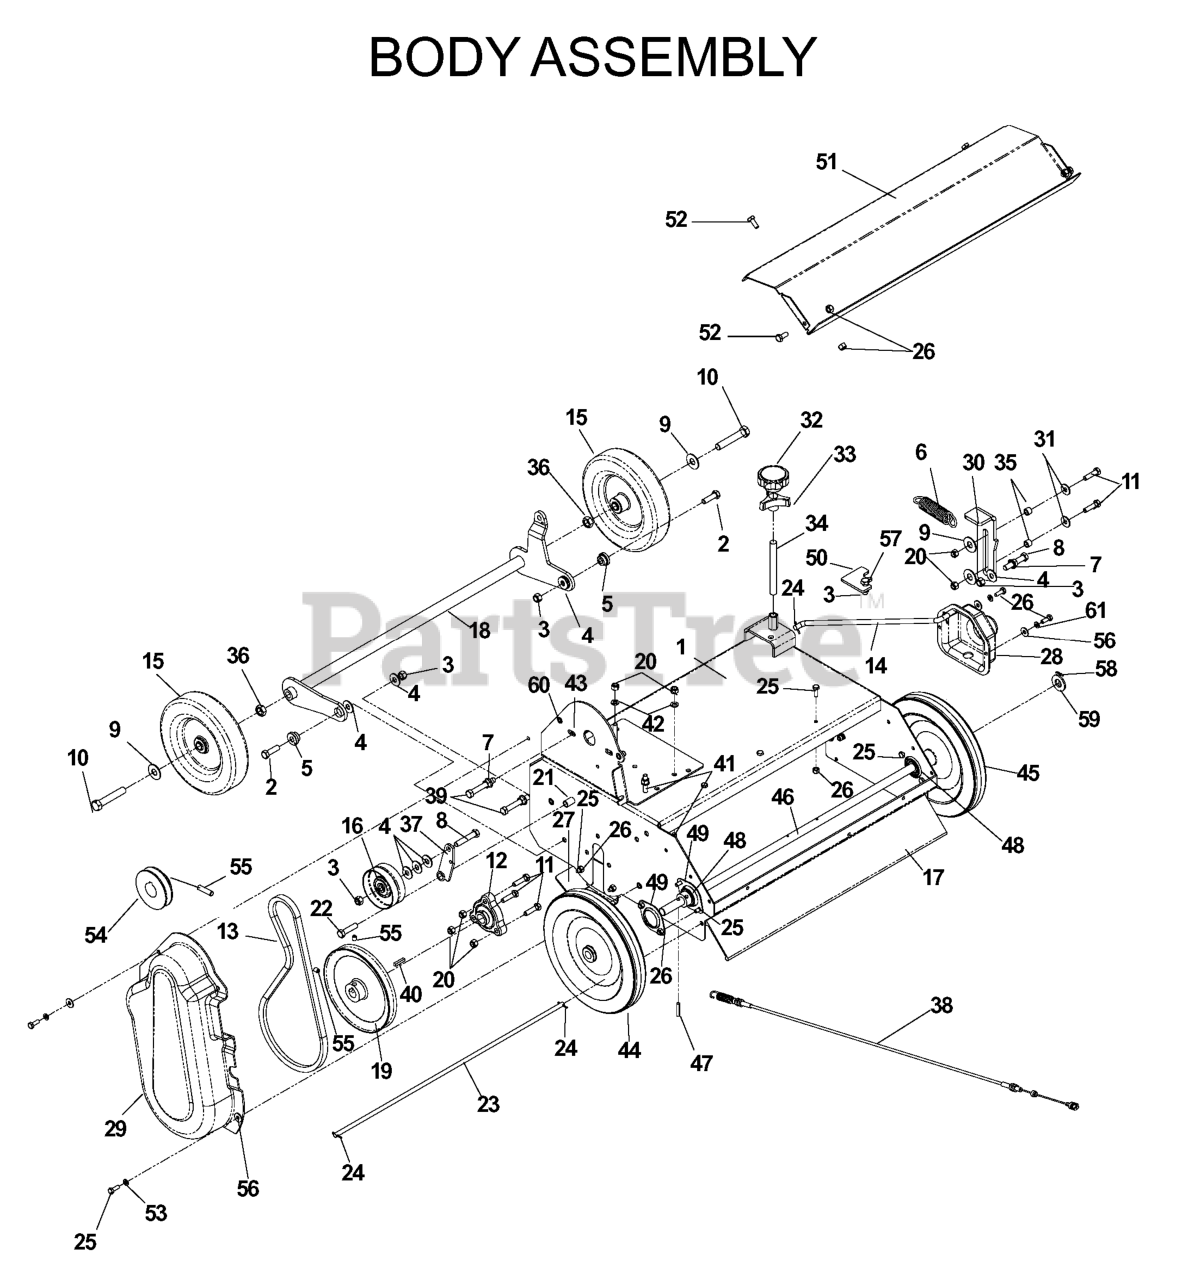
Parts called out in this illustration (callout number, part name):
1	BODY W/DECALS
2	HCS 3/8C X 1 1/4 GR5
3	NUT 3/8-16 NYLOC
4	WASHER 3/8 FLAT
5	BUSHING RAKE
8	HCS 3/8C X 2
9	WASHER 1/2 FLAT
10	HCS 1/2C X 2 3/4
11	HCS 5/16C X 1 1/4
12	BEARING, FLANGED
13	BELT, DRIVE RAKE/SLICER DFS
15	WHEEL 8 X 1 3/4 RAKE
16	PULLEY, IDLER 3 1/4 OD PAINTED
18	FRONT AXLE
19	PULLEY, MAIN SHAFT
20	NUT 5/16 NYLOC
21	BEARING, ONLITE RAKE/DT
22	HCS 3/8C X 1 1/2
24	COTTER PIN 3/32 X 3/4
25	HCS 1/4C X 3/4 HCS
26	NUT.1/4-20.HEX.NYLOC.ZD
27	SKID PLATE
28	SHAFT GUARD
29	BELT SHIELD POWER RAKE
31	WASHER 5/16 FLAT
34	R/B 108588 STUD, THREADED
36	NUT 1/2 HEX JAM
37	IDLER ARM - ORANGE
38	CABLE POWER RAKE
39	HCS 3/8C X 2 1/2
40	R/B 910061 KEY 3/16 SQ. X 1 LG
41	HCS 5/16C X 1 3/4
42	WASHER.LOCK.HVY.HLCL.SPR.5/16
43	BACKING PLATE ORANGE
44	WHEEL 10 X 1 3/4
45	WHEEL 10 X 1 3/4
46	AXLE, REAR
47	DNB BUSHING STEERING Y
48	BEARING - 5/8" W/COLLAR
49	FLANGE BEARING ZINC PLATED
50	DEPTH SHIM
51	REAR COVER ORANGE
52	HCS 1/4C X 5/8
53	LOCKWASHER 1/4"
54	PULLEY, ENGINE DRIVE
55	SET SCREW 5/16 NYLOC
56	WASHER 1/4 FLAT
57	HCS 3/8-16X1.GRD.5.ZD
58	COTTER PIN
59	WASHER
60	KNURLED INSERT
